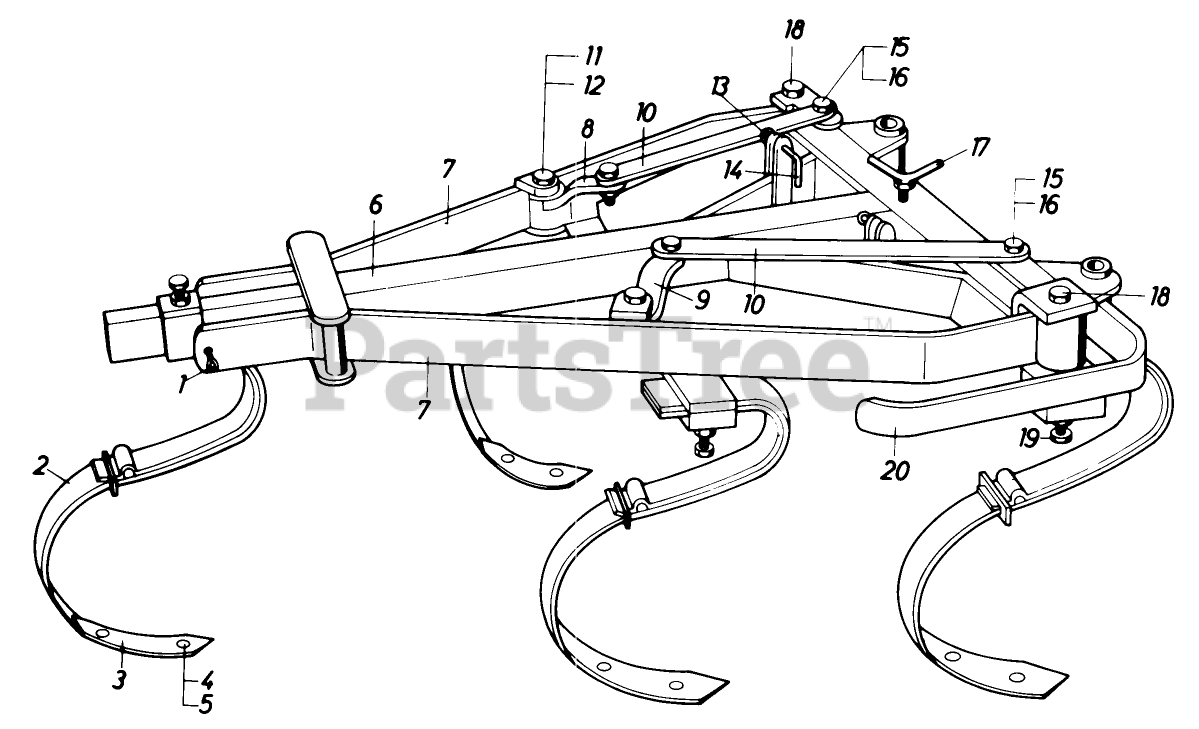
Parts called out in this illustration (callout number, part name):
2	Tooth
3	Reversible Blade
6	Frame Assembley
7	Side Support
8	Pivot Arm (Left)
